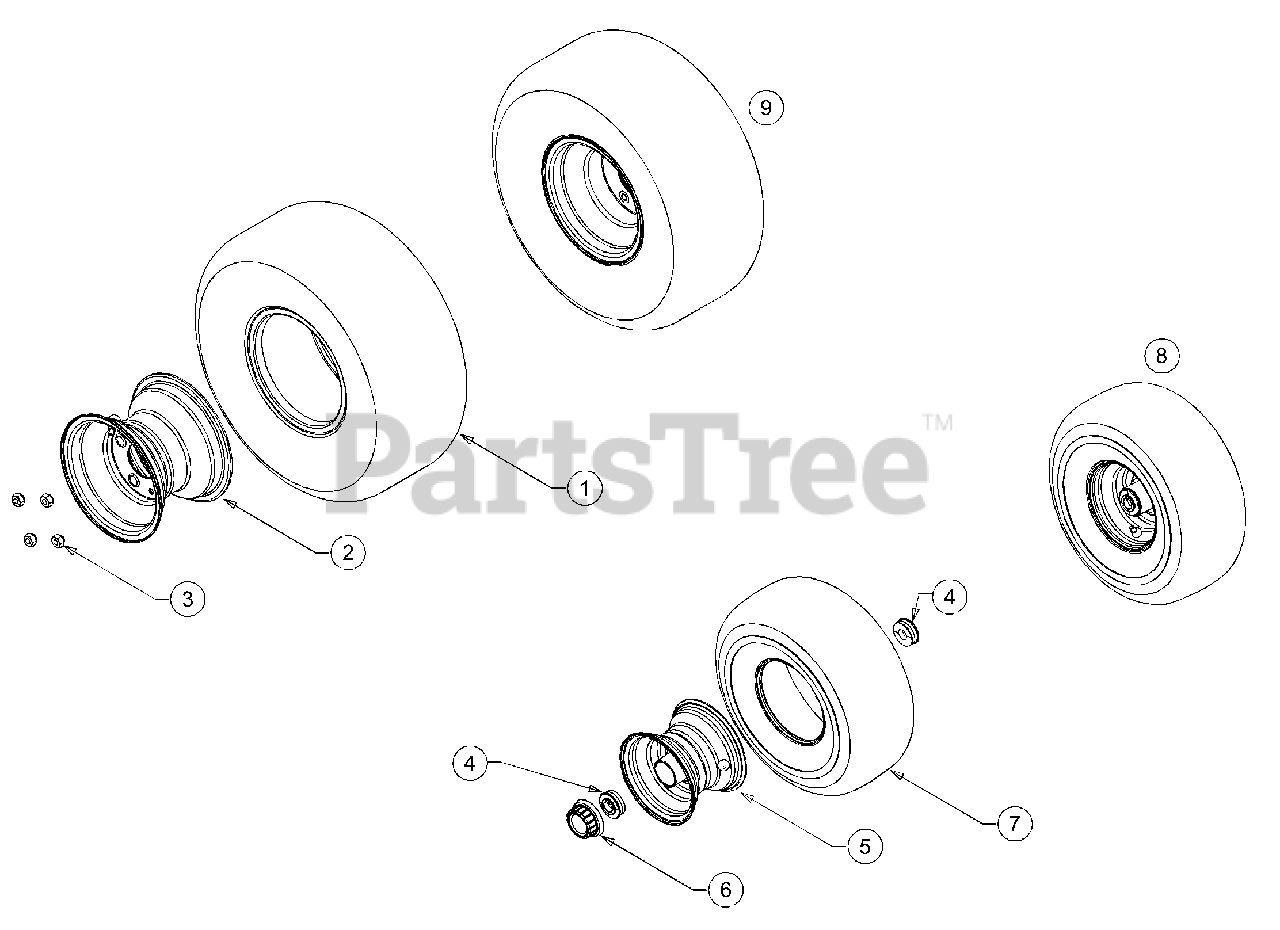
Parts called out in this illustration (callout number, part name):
1	Tire, Turf, Cub Cadet 20 x 9 x 8
3	Lug Nut, 7/16-14
4	Bearing, Ball, .75 ID x 1.75 OD
6	Hub Cap
7	Tire, Turf, Cub Cadet 15 x 6 x 6
8	Wheel Assembly, Cub Cadet 15 x 6 x 6
9	Wheel Assembly, Cub Cadet 20 x 9 x 8
